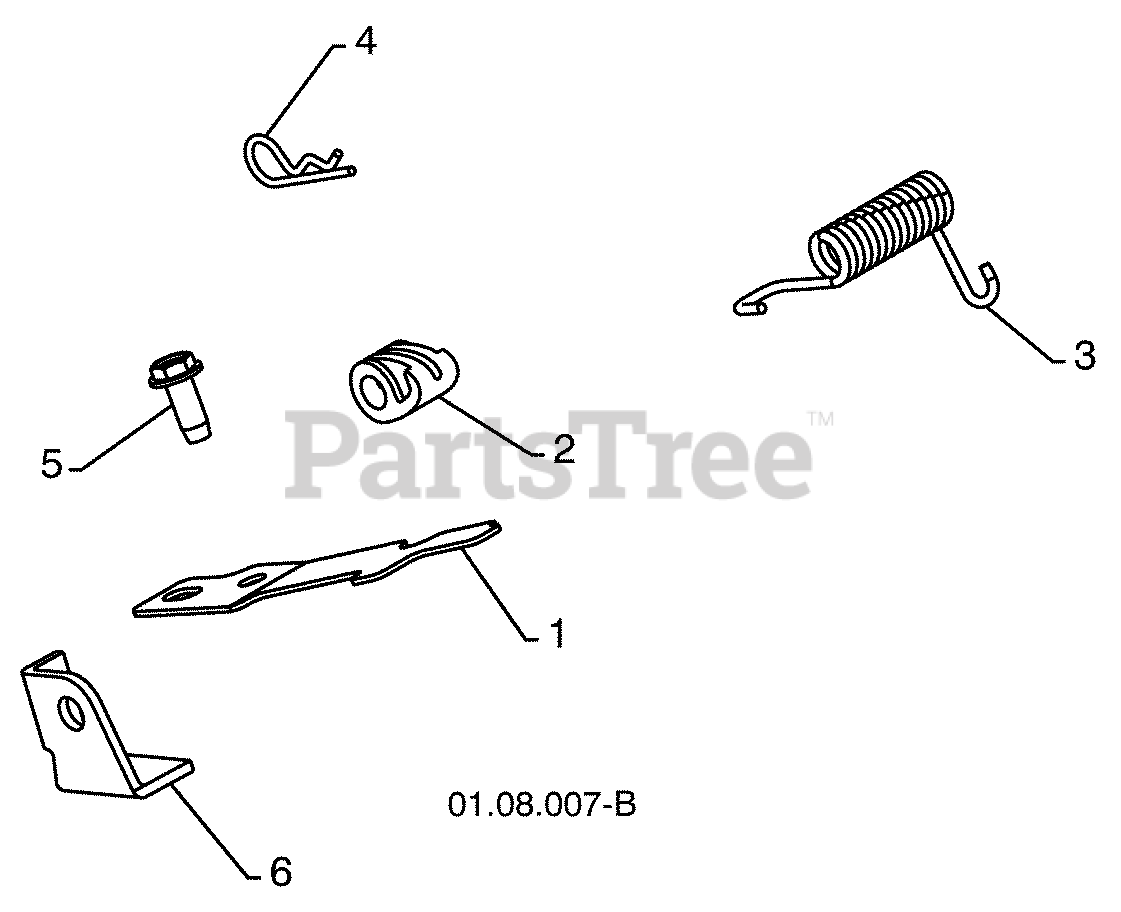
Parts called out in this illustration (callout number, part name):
1	INTERLOCK SPRING
2	INTERLOCK CAM
3	TORSION SPRING
5	SCREW 1/4-20 X .625
6	INTERLOCK STOP
